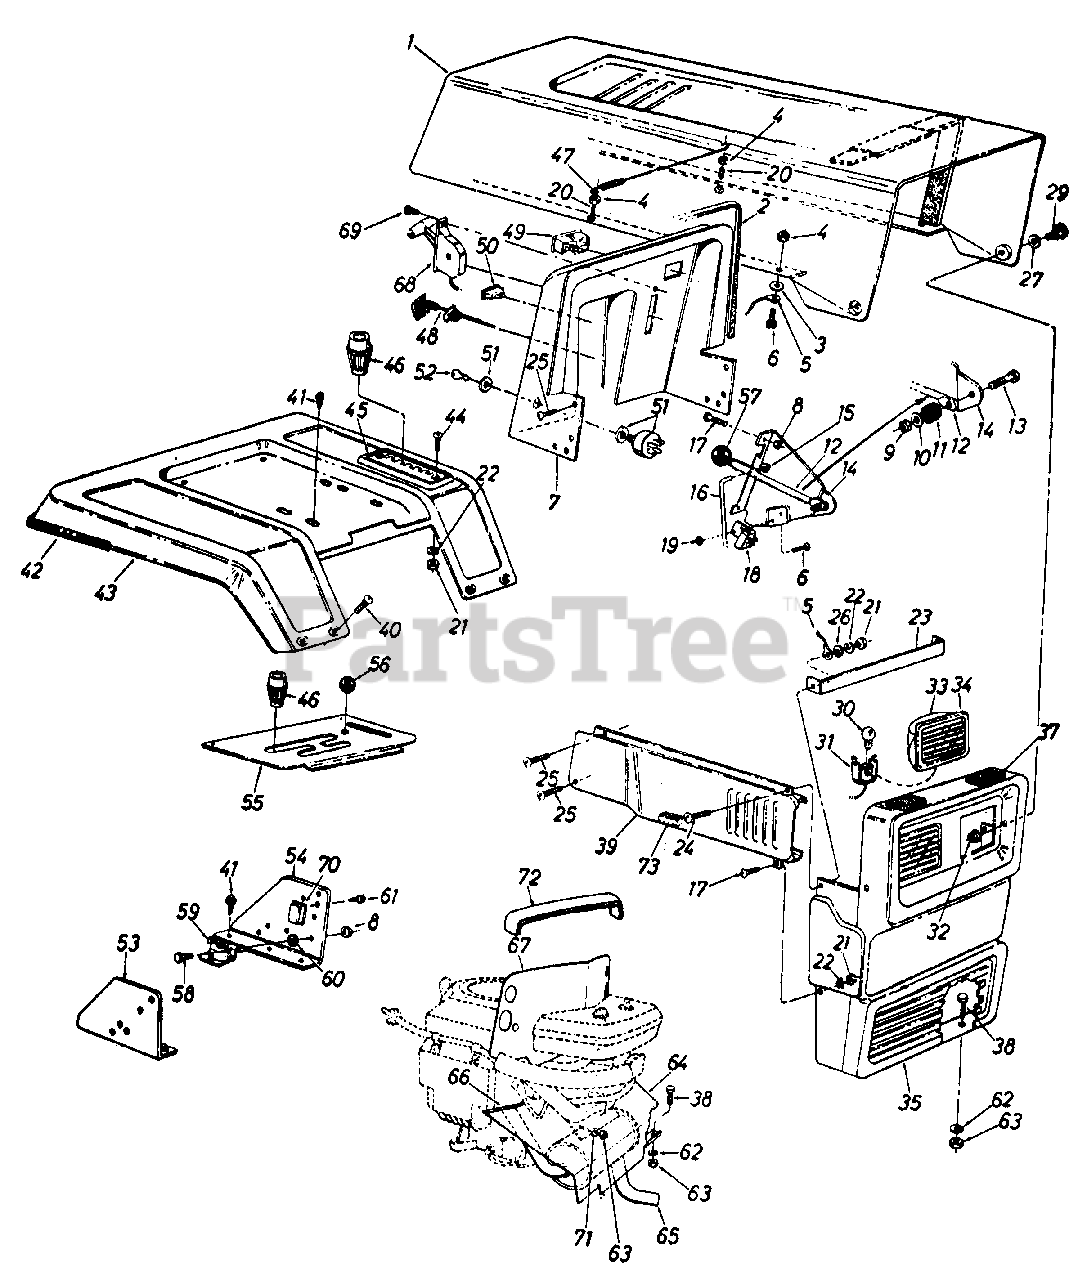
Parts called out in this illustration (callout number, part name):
3	Fl-Wash. .20" I.D. x .41" O.D.
4	Hex Sems Nut #10-24 Thd.
5	Hood Stop
6	Truss Mach. Scr. #10-24 x .5" Lg.
9	Hex L-Nut 1/4-20 Thd.
10	Fl-Wash. .281" I.D. x .73" O.D.
11	Rubber Washer
12	PTO Lever
13	Hex Bolt 1/4-20 x 1.25" Lg.
14	Deck Clutch Control Brkt.
15	Push Cap
16	Deck Control Rod
17	Truss Mach. Scr. 1/4-20 x .5" Lg.
18	Safety Switch
19	Hex Nut #10-24 Thd.
20	Hex Bolt 10-24 x 1.0" Lg.
21	Hex Nut 1/4-20 Thd.
22	L-Wash. 1/4" I.D.
23	Tie Strap Grille
24	Truss Mach. Scr. 1/4-20 x .75" Lg.
25	Hex TT-Tap Scr. 1/4 20 x .75" Lg.
26	FI Wash . .25" I . D. x .62"
27	Spr. Wash. .39" I.D. x .62"
29	Shld. Bolt .375" Dia. x .125" Lg.
30	Lamp
31	Socket
32	Locking Flange Nut 1/4 28 Thd.
33	Headlight Housing
34	Headlight Lens
38	Hex Bolt 5/16-18 x .75" Lg.
41	Hex Wash. AB-Tap Scr. 5/16 x .75" Lg.
42	Trim Strip-81" Lg.
43	Fender
44	Truss Mach. Scr. 1/4-20 x .62" Lg.
45	7-Speed Selector Plate
46	Shitt Knob
47	Hood Spring
48	Choke Control 46" Lg.
49	Ammeter
50	Light Switch
51	Ignition Switch
52	Ignition Key
53	Dash Support Brkt.-R.H.
54	Dash Support Brkt.-L.H.
55	Transmission Cover
56	Ball Knob
57	Knob-Blade Clutch
58	Hex Bolt 1/4-20 x .5" Lg.
59	Solenoid
60	Ext. L-Wash. 1/4n I.D.
61	Hex Wash. Hd. Scr. 1/4 x .5" Lg.
62	L-Wash. 5/16" I.D.
63	Hex Nut 5/16-18 Thd.
64	Front Heat Shield
65	Muftler
66	Trim Strip 10" Lg.
67	Top Shield
68	Throttle Control Box Ass'y.
69	Truss Mach. AB-Tap Scr. #10 x .5" Lg.
70	Circuit Breaker
71	Spec. L-Wash. 5/16" I.D.
72	PVC Foam
73	Rubber Strip
